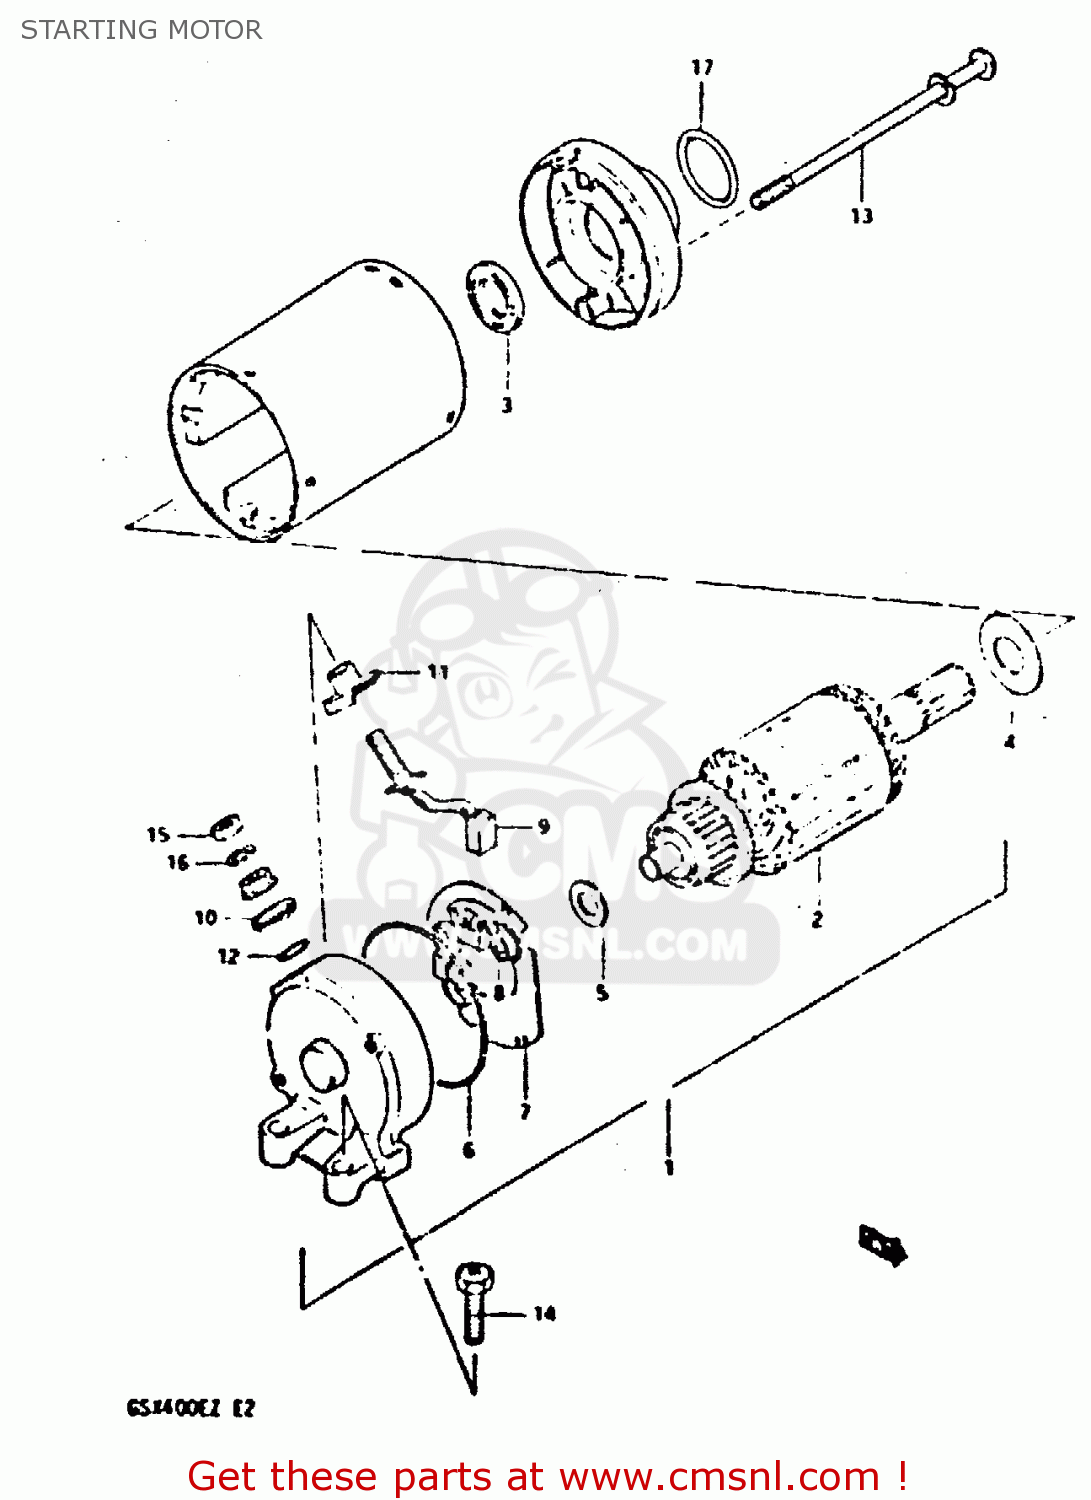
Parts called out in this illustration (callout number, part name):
1	MOTOR ASSEMBLY,STARTING
2	ARMATURE
3	SEAL,OIL
4	RING,SNAP
5	SHIM,ARMATURE
6	O RING
7	HOLDER,BRUSH
8	SPRING
9	BRUSH (+)
10	BUSHING (1)
11	BUSH,NO.2
12	O-RING
13	BOLT,STARTING MOTOR HOUSING
14	BOLT
15	NUT 6MM
16	LOCK WASHER
17	O RING(D:2,ID:24.5)
